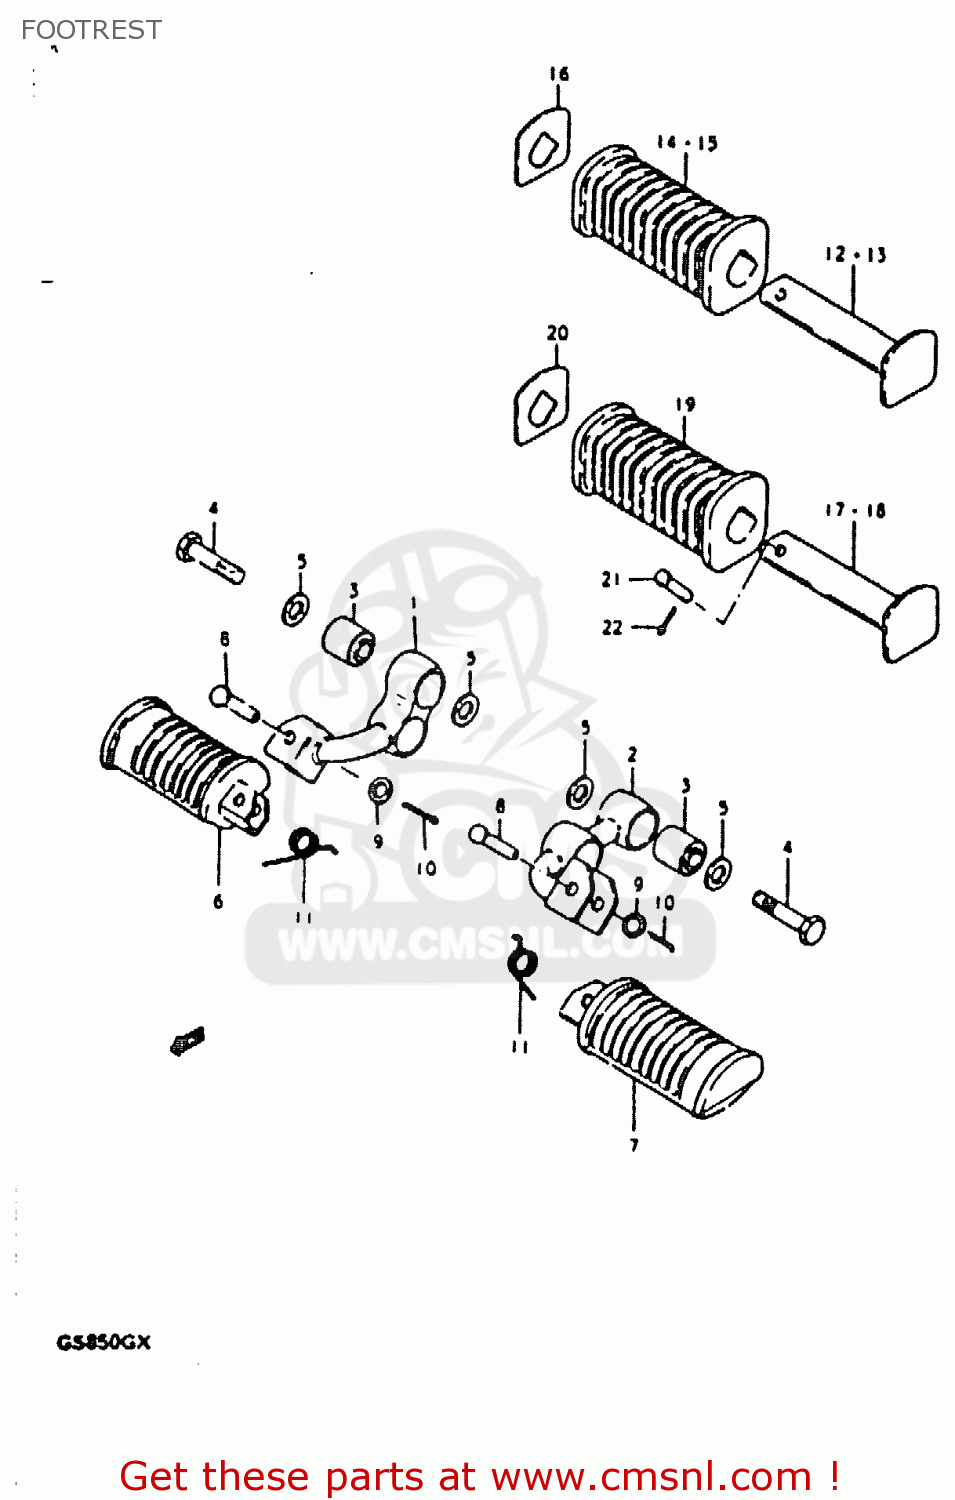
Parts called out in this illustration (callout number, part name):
1	BAR,FRONT FOOTREST,RIGHT
2	BAR,FRONT FOOTREST,LEFT
3	BUSH
4	BOLT
5	WASHER (10.1X21X2.3)
6	RUBBER,FRONT FOOTREST
7	FOOTREST
8	PIN
9	WASHER
10	PIN
11	SPRING
12	BAR,REAR FOOTREST
13	BAR,REAR FOOTREST
14	RUBBER,PILLION FOOTREST
15	RUBBER, LH
16	WASHER,REAR FOOTREST RUBBER
17	BAR,REAR FOOTREST,RIGHT
18	BAR,REAR FOOTREST,LEFT
19	RUBBER,PILLION FOOTREST
20	WASHER,PILLION FOOTREST RUBBER
21	PIN
22	PIN
